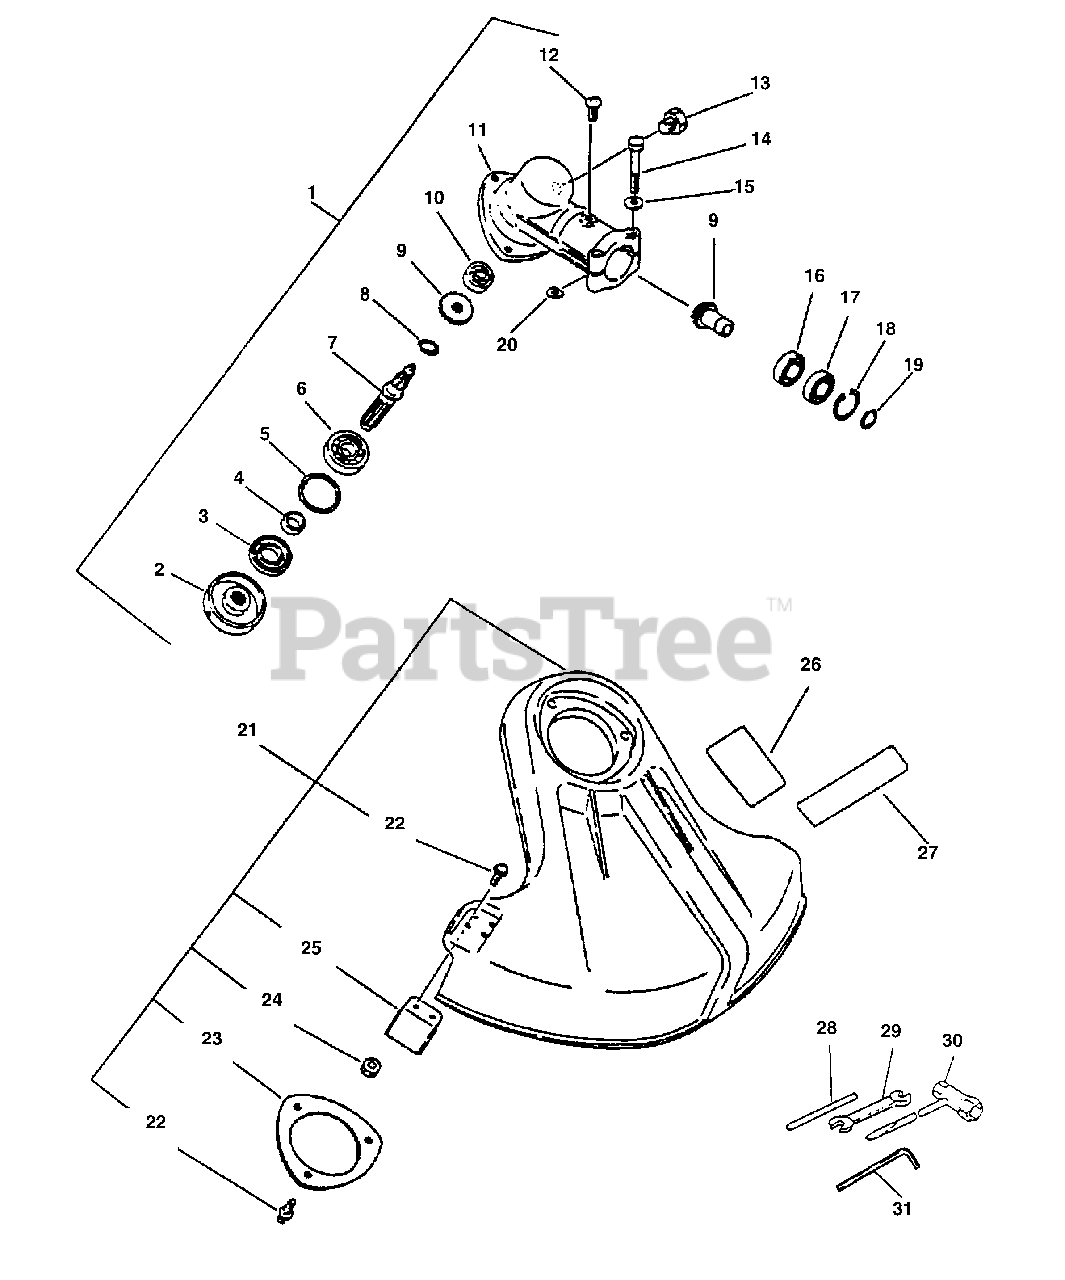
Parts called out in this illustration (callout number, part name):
1	GEAR CASE ASSY
2	ADAPTOR, BLADE - UPPER
3	SEAL, OIL
5	RING, RETAINING - 32
6	BEARING, BALL - 6201
7	GEAR - SHAFT
8	RING, RETAINING - 10
9	GEAR SET - BEVEL
10	BEARING, BALL - 609
11	CASE, GEAR
12	SCREW - 5X10
13	BOLT - 8X8
14	BOLT - 5X35
15	WASHER - 5
16	BEARING, BALL - 6900
17	BEARING, BALL - 6900Z
18	RING, RETAINING - 22
19	RING, RETAINING - 12
21	DEBRIS SHIELD KIT
22	SCREW - 5X16
23	PLATE, SHIELD
25	KNIFE, TRIMMER LINE
26	LABEL - CAUTION
27	LABEL - ECHO
28	LOCKING TOOL
29	SPANNER - 8X10mm
30	T-WRENCH - 17X19mm
31	HEX KEY - 3mm
